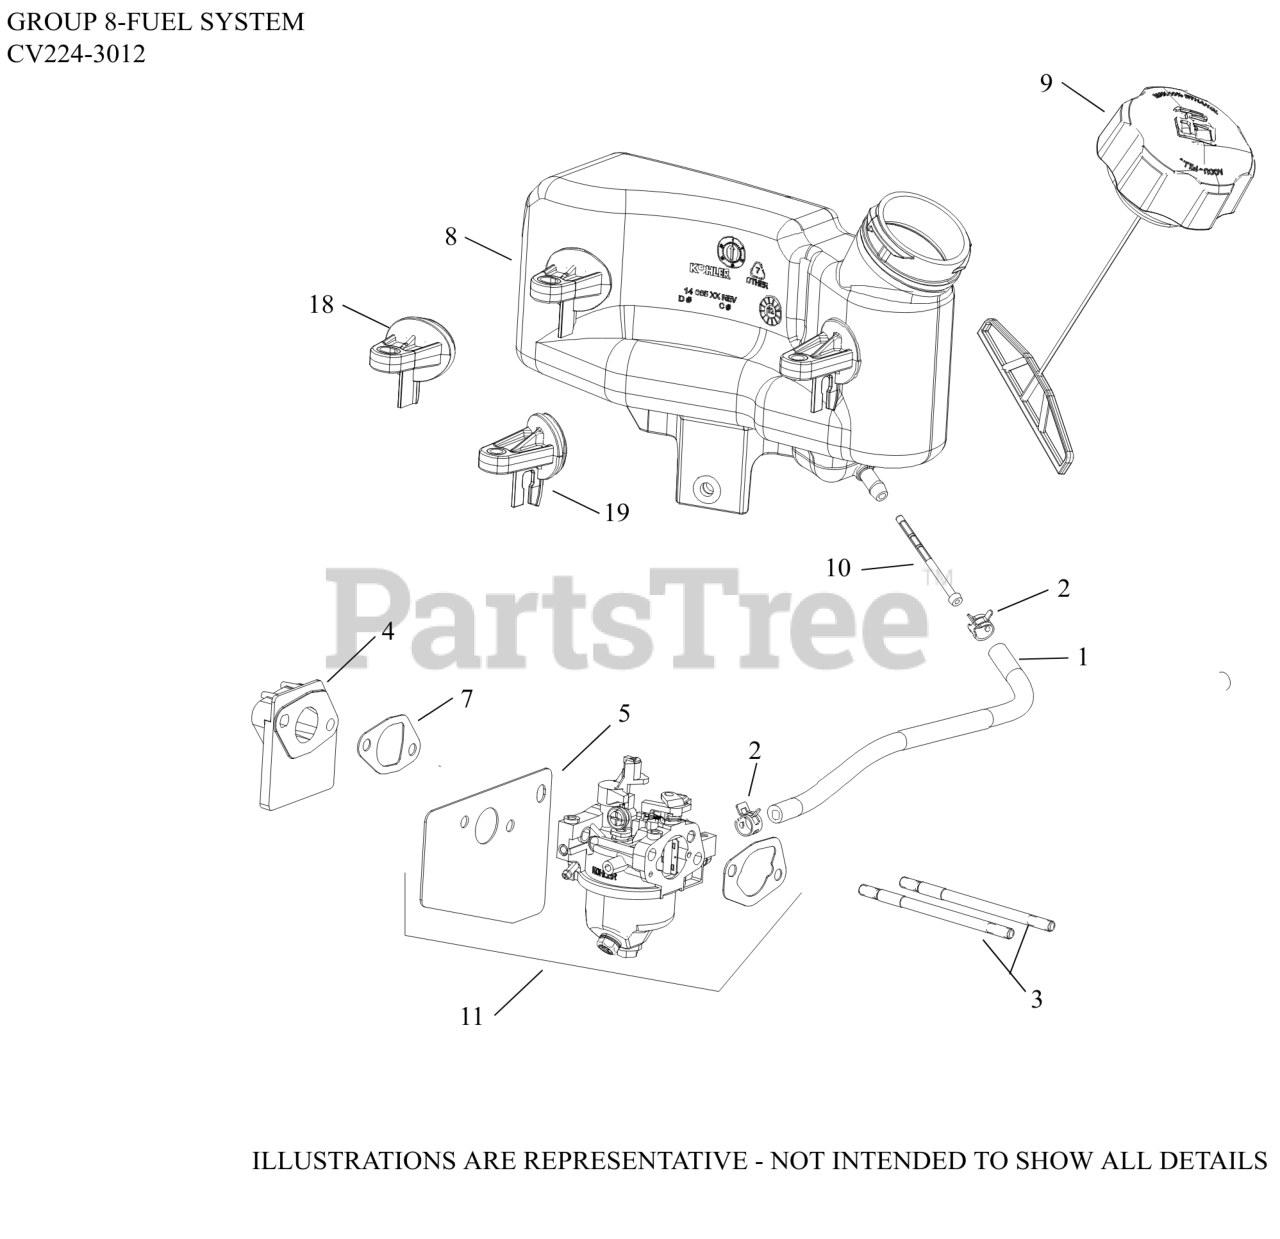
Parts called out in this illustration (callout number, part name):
1	HOSE, FUEL LOW-PERMEATION
2	CLAMP, HOSE (NON-CALIF)(#1423710S)
3	STUD,M6X1.0X100.2MM
4	KIT, SPACER
5	KIT, CARBURETOR HEAT SHIELD GASKET
7	KIT, INTAKE GASKET
8	TANK, FUEL
9	FUEL CAP ASSEMBLY
10	FILTER, FUEL IN-NIPPLE
11	KIT, CARBURETOR COMPLETE
18	BRACKET, FUEL TANK
19	BRACKET, FUEL TANK
NI	TOOL, SPARK PLUG WRENCH ASSY
NI	KIT,HIGH AL(4000-8000 FT)USE 14 755 04-S
NI	KIT, CARBURETOR REPAIR (RUIXING)
